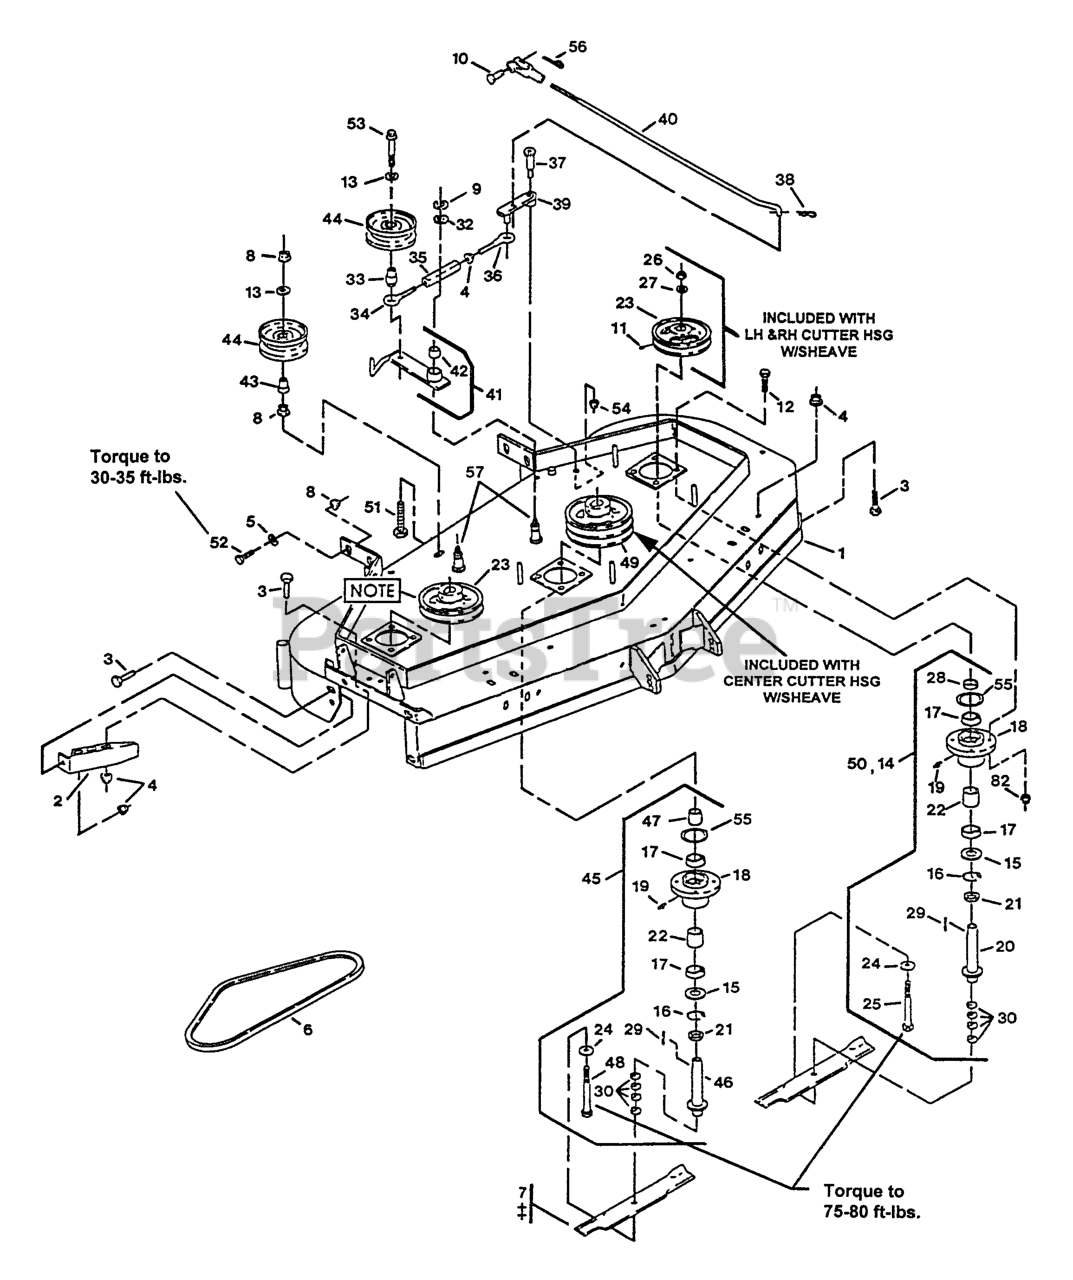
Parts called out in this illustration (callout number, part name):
2	WLD, DISCHARGE BAFFLE
10	PIN-CLEVIS
11	SCREW-SET
14	ASM,HOUSING CUTTER
15	SEAL,DUST
16	RING,SNAP WLDS N5000-244
17	BEARING,HD SPINDLE
18	HOUSING,CUTTER
21	SPACER,BEARING &SPINDLE
22	SPACER,BRG/BRG
24	WASHER-SPRING
25	SCREW-CAP, HH
27	WASHER-RETAINER, SHEAVE
31	YOKE-ADJUSTABLE
32	WASHER-SPINDLE
33	BUSHING-ENGAGEMENT
34	EYEBOLT-THREAD, LH
35	BODY-TURNBUCKLE
36	EYEBOLT-THREAD, RH
37	BOLT,SHLDR KSKH
38	PIN-COTTER
40	LINKAGE
42	BEARING,POWDERED METAL
43	BUSHING,IDLER
47	SPACER,BEARING/SHEAVE
48	SCRW,CAP HH 5/8-18X8.5
51	BOLT,TAP HH3/8-16X2-1/4
